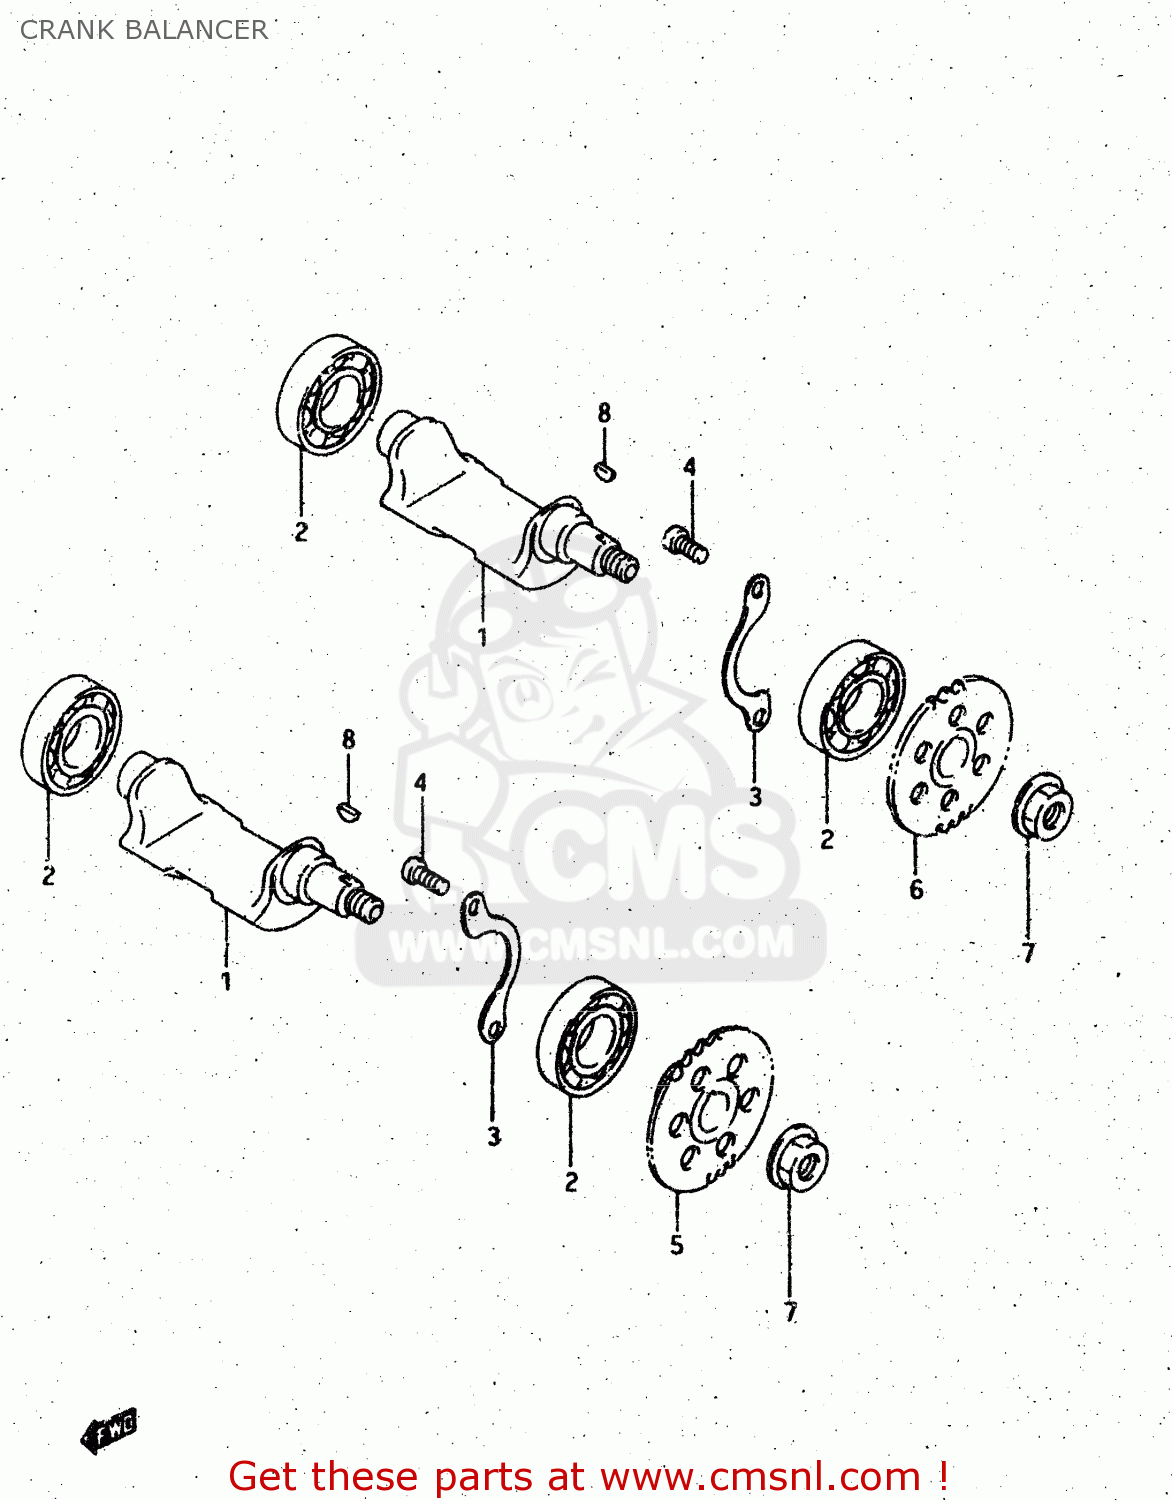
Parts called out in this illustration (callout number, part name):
1	BALANCER,CRANKSHAFT
2	BEARING
3	RETAINER,CRANK BAL BEARING
4	SCREW
5	SPROCKET,BALANCER DRIVE
6	SPROCKET,BALANCER DRIVE
7	NUT
8	KEY
